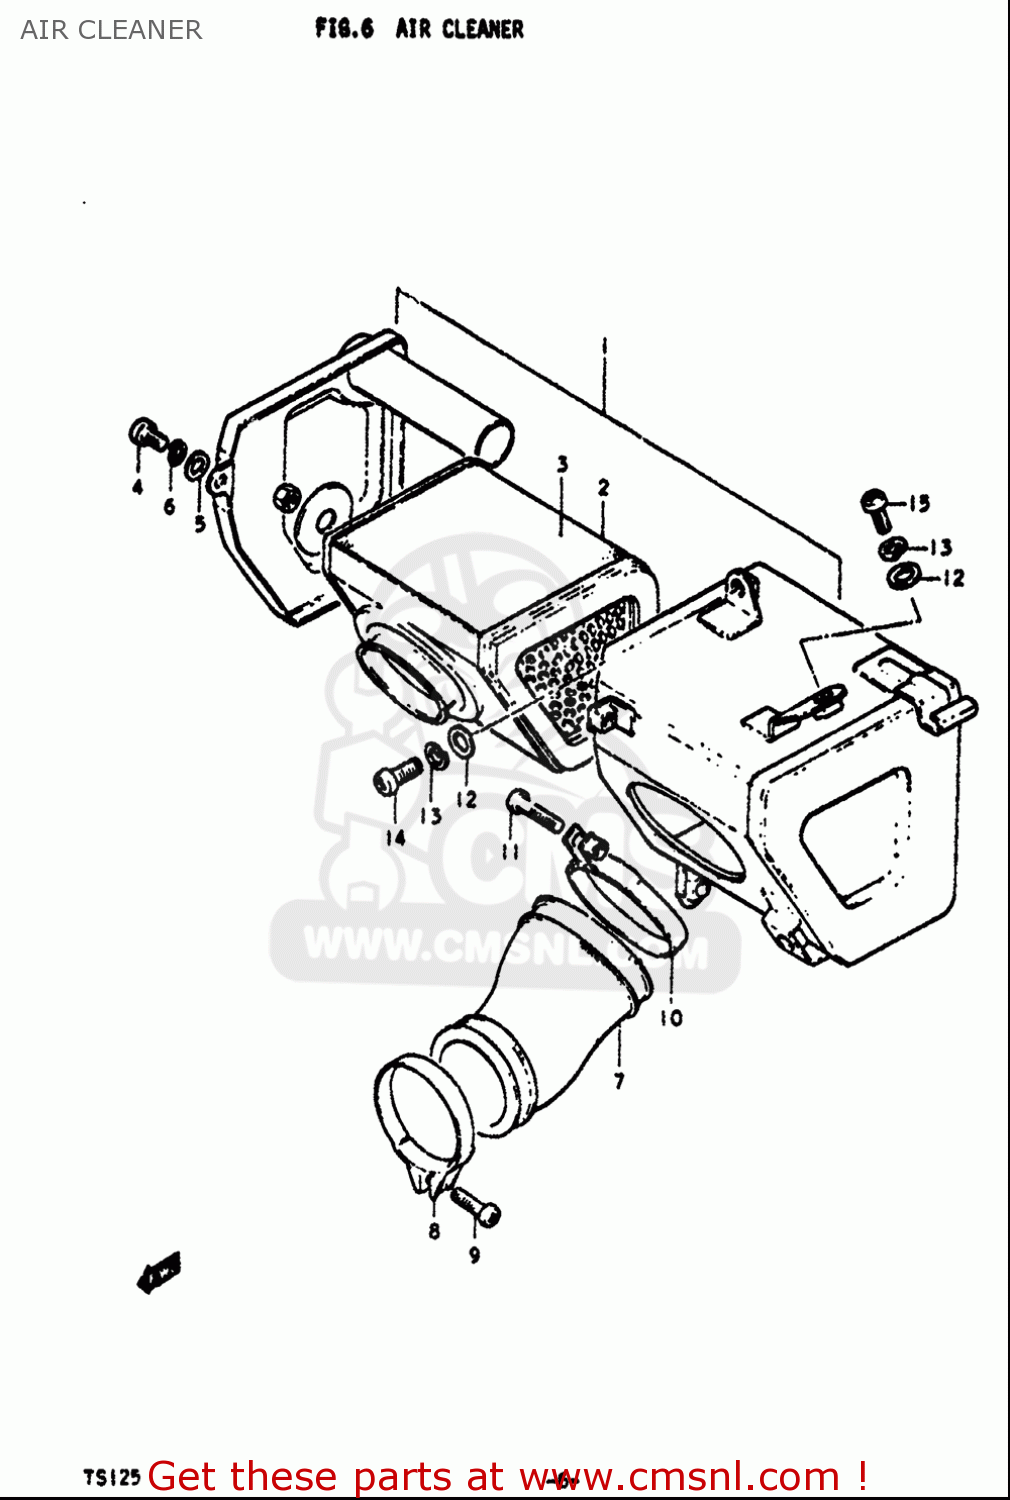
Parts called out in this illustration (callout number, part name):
3	FILTER
4	SCREW
5	WASHER
6	WASHER,LOCK
7	HOSE,CARBURETOR AIR INLET
8	CLAMP
9	SCREW
10	CLAMP
11	SCREW
12	WASHER
13	WASHER,LOCK
14	SCREW
15	SCREW
